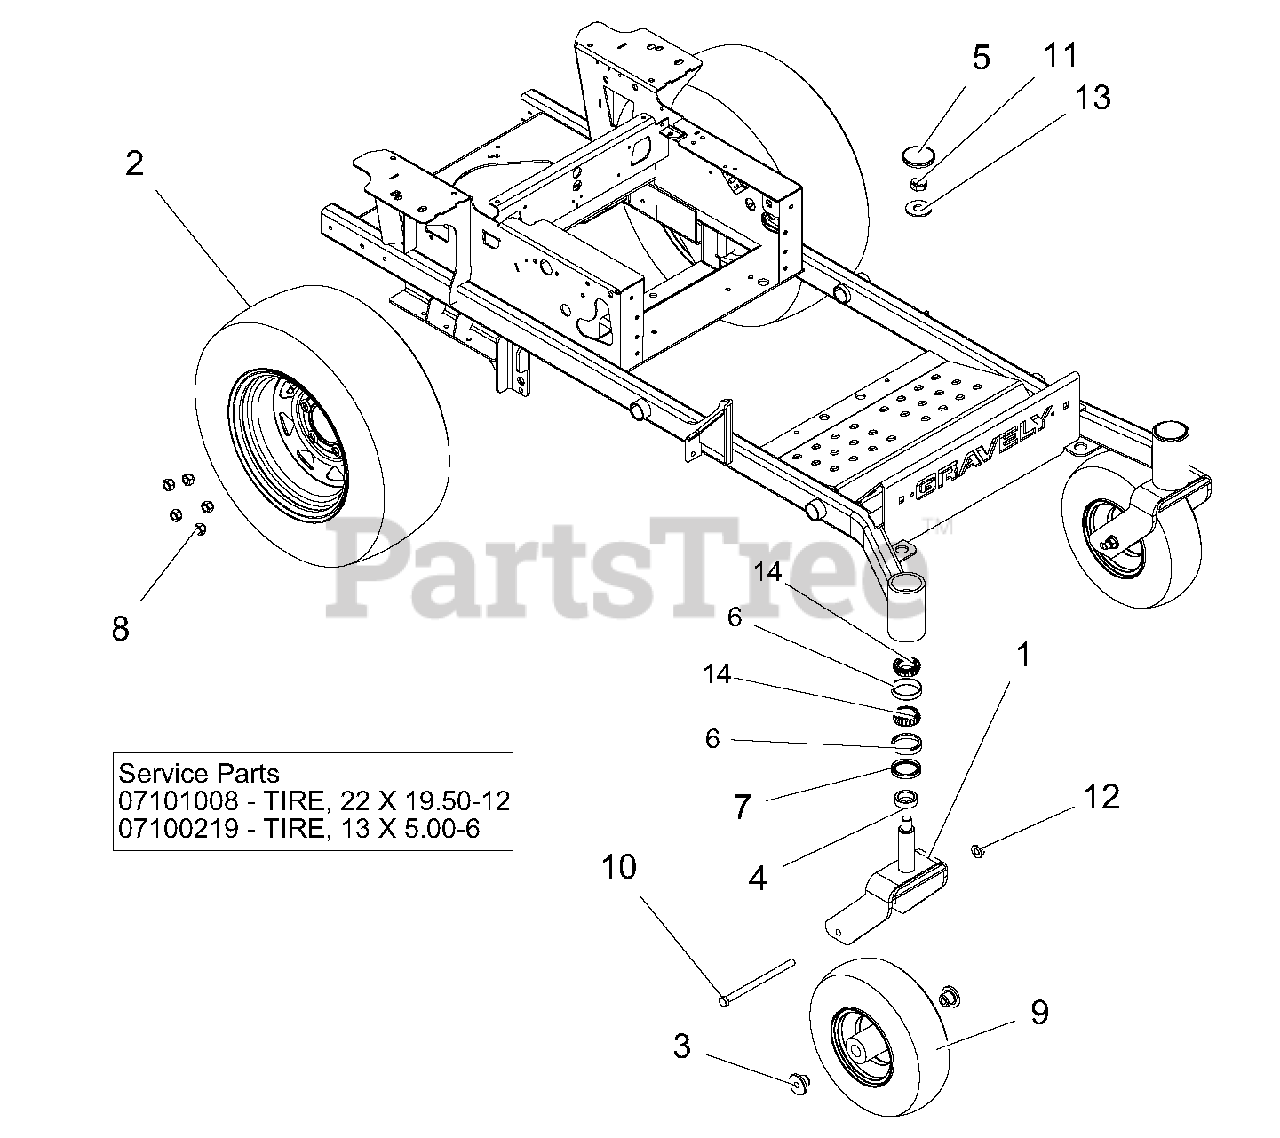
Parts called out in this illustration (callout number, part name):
1	WLDMT, CASTER FORK-RED
2	TIRE/WHEEL, ASSEMBLY 22X9.5-12
3	SPACER, FRONT WHEEL
4	SPACER-1.258 ID X 1.750 OD X .550
5	CAP, DUST
6	BRG, CUP 2.328X.465
7	SEAL, OIL 1.75 X 2.332 X .312
8	NUT, 1/2-20 LUG C
9	TIRE/WHEEL, ASM , 13X5-6
10	@BLT-HEX .50-13X7.50 GR5 YWZC
11	@NUT-LK-CTR-JAM .75-16 YWZC
12	NUT-LK-NYL-FLG .50-13 YWZC
13	@WSHR-FL-STL.812X2.00X.148YWZC
14	BRG, CONE 1.25 X .66
